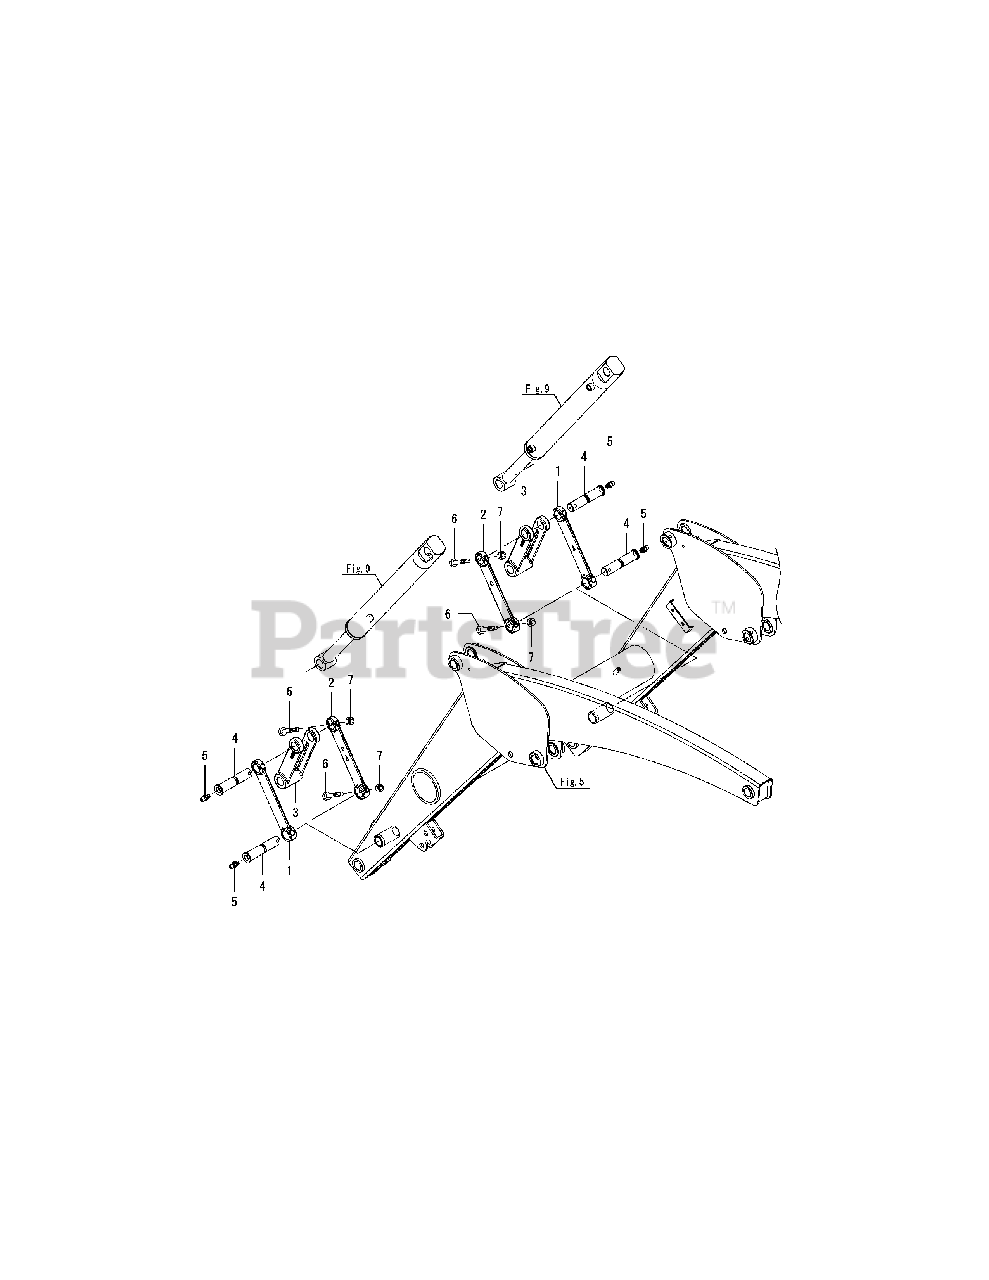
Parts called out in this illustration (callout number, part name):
3	DUMP LINK FRONT
4	9/8 STEPPED PIN 140
5	NIPPLE M6F, GREASE
6	BOLT M 8X 60 PLATED
